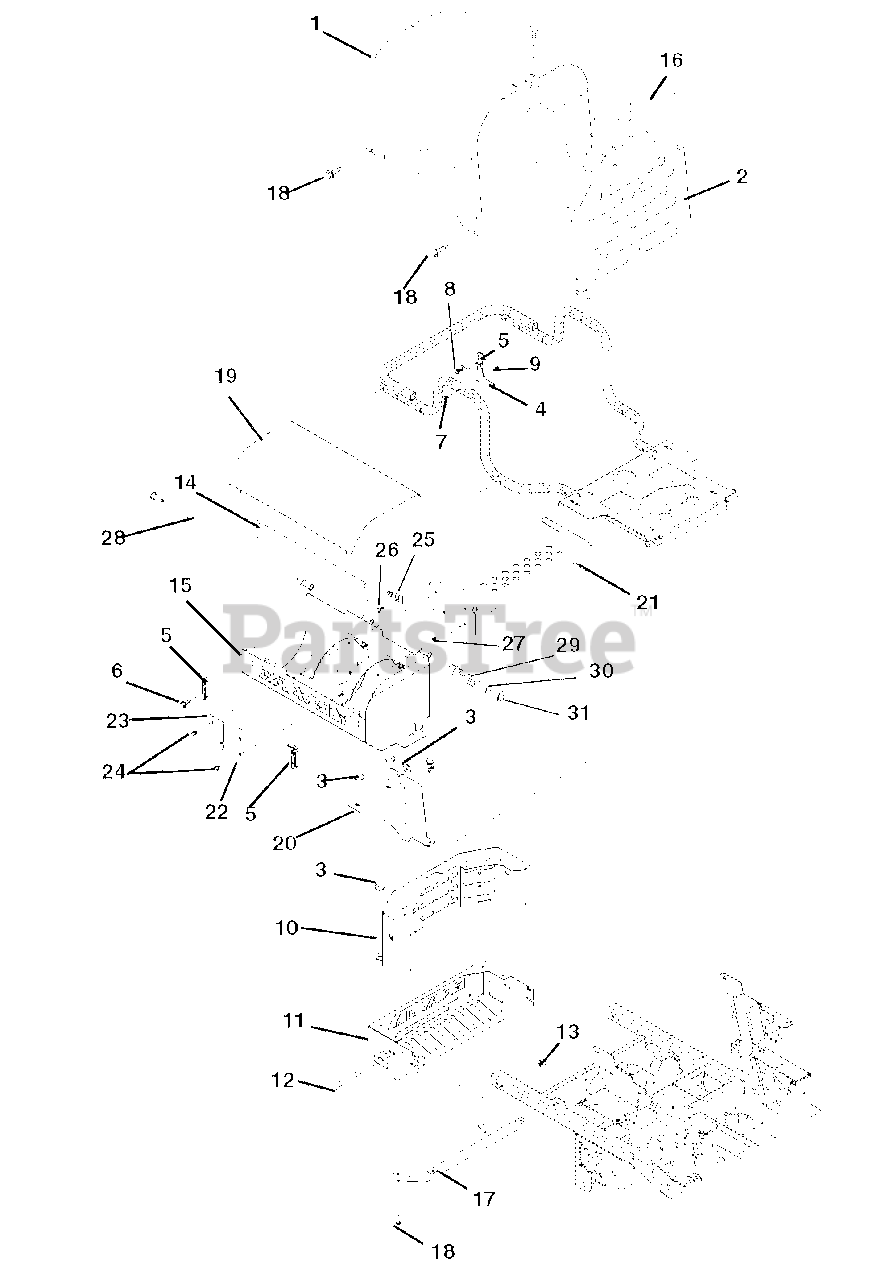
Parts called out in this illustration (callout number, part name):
1	Hood, 200 XDZ LPG
2	Shroud, Hood
3	Washer, Flat Steel .406 x 1.50 x .245
4	Bracket, Latch Stop
5	Latch, Rubber
6	Screw, Machine 10-24 x .50 Hex Washer Head
7	Screw, Machine 10-24 x 1.50 Hex Washer Head
8	Button Bumper
9	Nut-Spin Lock-Flange .312-18
10	Guard, Rear Engine 200 XDZ LPG
11	Bumper, Rear
12	Bolt, Hex .38-16 x 2.75 Grade 5
13	Nut-Locking-Top-Flange .38-16
14	Plate, Name Backer LPG
15	Weldment, Tank Housing RH
16	VHB Tape 4941F
17	Heat Shield
18	Screw-Tapping .38-16 x .50 Hex Washer Head Thread Rolling YWZ
19	Weldment, Cover Tank RH LPG
20	Weldment, RH Tank Support
21	Weldment, Tank Support
22	Plate, LPG Tank Support Backer
23	Plate, LPG Tank Support Backer
24	Bolt, Round Head Square neck .38-16 x 1.25
25	Thumb Latch
26	Screw, Machine 10-24 x .50 Hex Washer Head
27	Nut, Locking-Nylon 10-24 with Insert
28	Rod, Tank Cover Hinge LPG
29	Spring, Compression .055 x 4.5
30	Bushing-Flange
31	Ring, Retaining-External .500 x .050
